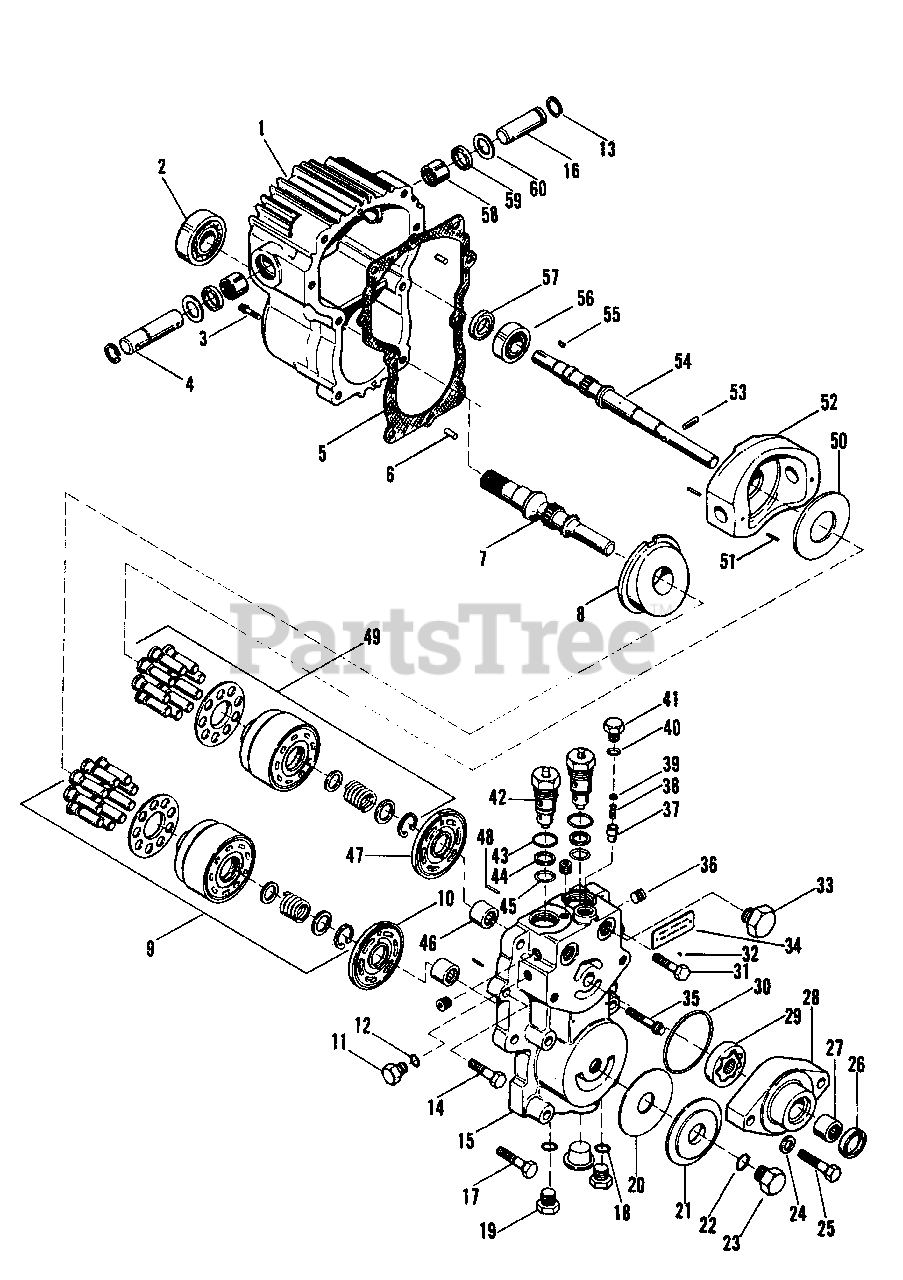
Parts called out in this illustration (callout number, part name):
2	BALL BEARING
3	12 PT. CAPSCREW
6	HEADLESS STR. PIN
7	MOTOR SHAFT
8	SWASH PLATE
9	CYL. BLOCK KIT
10	VALVE PLATE
11	PLUG, Hex Head
13	RING, Retaining
14	CAPSCREW, Hex head
15	CENTER SECTION
17	CAPSCREW, Hex head
19	PLUG, Hex head
21	FILTER COVER PLATE
23	SPECIAL PLUG
24	WASHER, Flat
25	CAPSCREW, Hex head
26	SEAL, Lip
27	NEEDLE BEARING
28	CHARGE PUMP HOUSING
29	GEROTOR ASSY.
30	"O" RING
31	CAPSCREW, Hex head
32	DRIVE SCREW
33	STR. THD. HEX PLUG
34	NAME PLATE
35	12 PT. CAPSCREW
37	RELIEF VALVE CONE
38	RELIEF VALVE SPRING
40	"O" RING
41	PLUG, Hex head
42	CHECK VALVE ASSY.
43	O-RING
44	BACK-UP RING
45	"O" RING
46	NEEDLE BEARING
47	VALVE PLATE
48	PIN, STR. HEADLESS
49	CYL. BLOCK KIT
50	THRUST PLATE
51	COILED SPRING PIN
52	SWASH PLATE
53	HEADLESS STR. PIN
55	WOODRUFF KEY
56	BALL BEARING
58	NEEDLE BEARING
